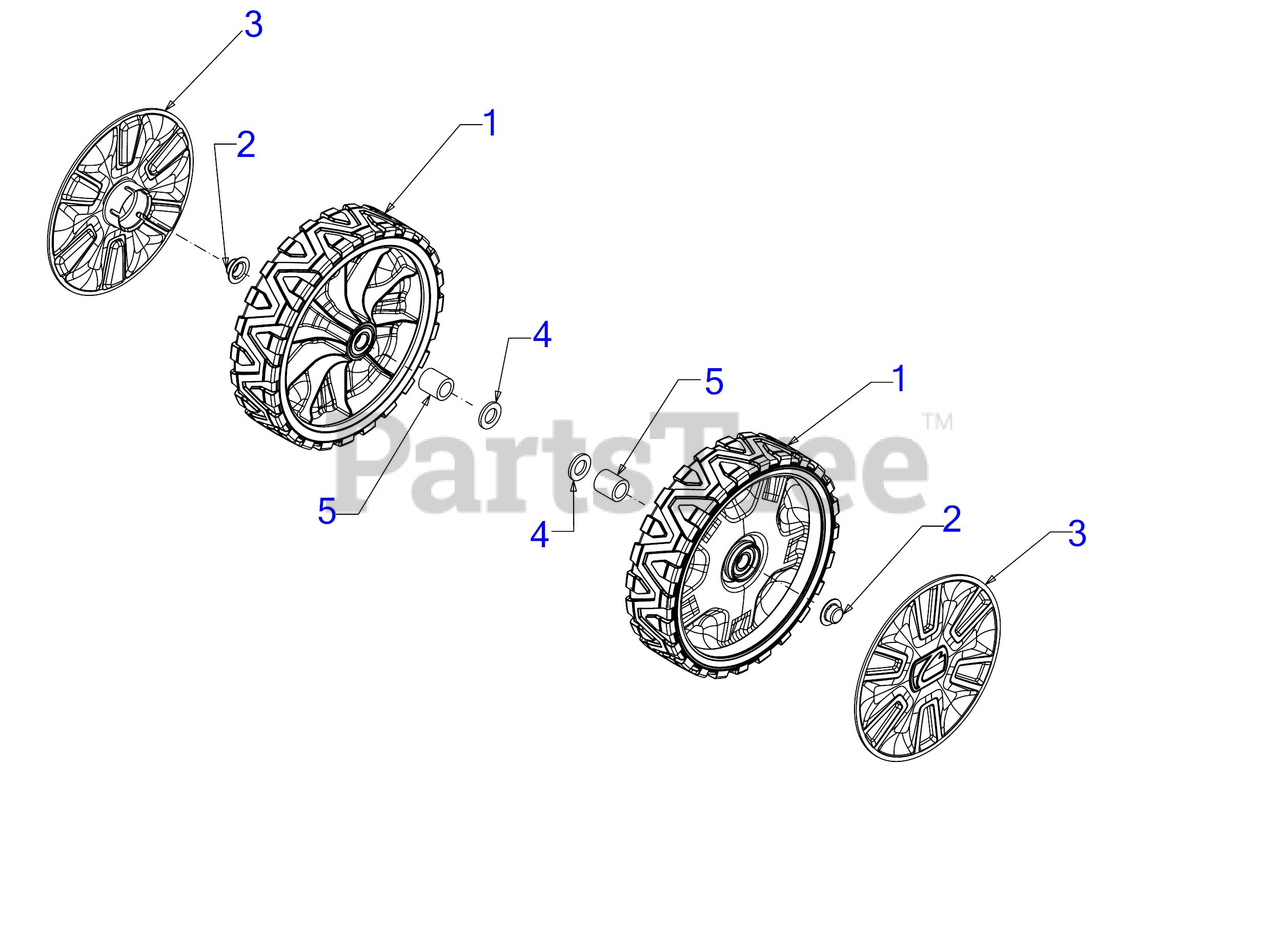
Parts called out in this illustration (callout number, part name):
1	WHEEL ASSEMBLY (8 x 2)
3	HUBCAP-8" CUB
4	FLAT WASHER .535 x .930 x .090
5	SPACER .525 x .775
